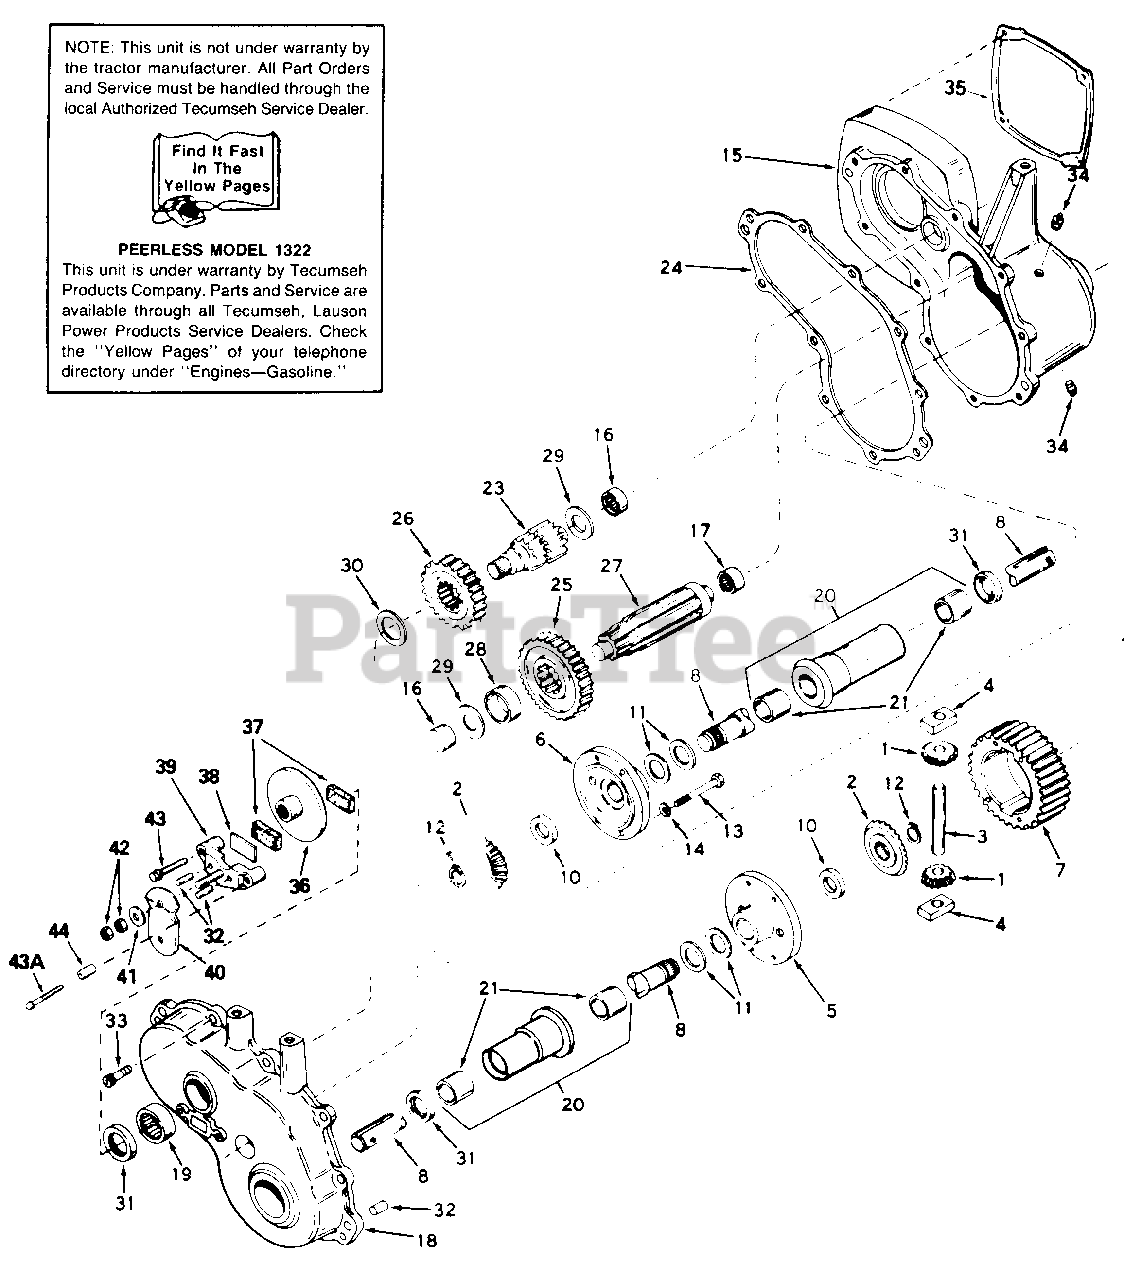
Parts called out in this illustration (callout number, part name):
1	Pinion: Bevel
2	Gear: Bevel
3	Pin: Drive
4	Block: Drive
5	Carrier: Differential
6	Carrier: Differential
7	Gear: Ring
8	Axle
10	Washer
11	Washer: Thrust
12	Ring: Snap
13	Screw: Hex Hd. 1/4-20 x 2 1/4
14	Lock Washer: 1/4"
15	Case Ass'y.
16	Bearing: Needle
17	Bearing: Needle
18	Cover Ass'y.
19	Bearing: Needle
20	Housing Ass'y.: Axle
21	Bushing
23	Shaft: Brake
24	Gasket: Case to Cover
25	Gear: Output
26	Gear: Idler
27	Shaft: Output
28	Spacer
29	Washer
30	Washer
31	Seal: Oil
32	Pin: Dowel
33	Screw: Hex Hd.: Self-Tapping: 1/4-20 x 1
34	Plug: Pipe
35	Gasket
36	Disc: Brake
37	Pad: Brake
38	Plate: Brake Pad
39	Holder: Brake Pad
40	Lever: Brake
41	Washer: Flat
42	Lock Nut 5/16-24
43	Screw: Hex Hd.: Self-Tapping: 1/4-20 x 11/4
43A	Screw: Hex Hd.: Self-Tapping: 1/4-20 x 21/4
44	Spacer
